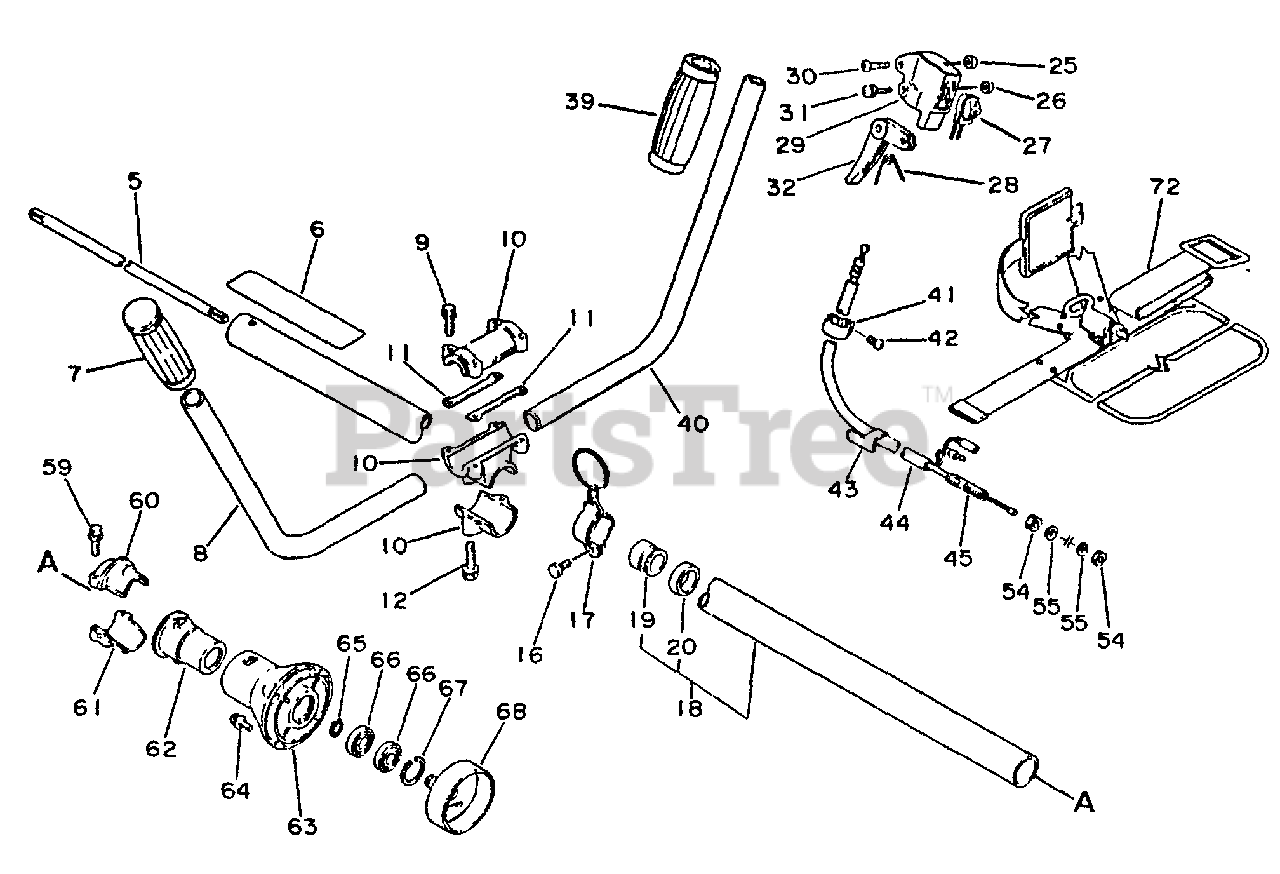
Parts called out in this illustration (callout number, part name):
5	DRIVESHAFT - SOLID
6	LABEL - CAUTION
7	GRIP, HANDLE - LEFT
8	HANDLE, FRONT - LEFT
9	SCREW - 5X25
10	HANDLE BRACKET KIT
12	SCREW - 6X30
16	HANGER KIT
17	BOLT - 5X12
18	MAIN PIPE ASSY
25	LOCKNUT - 5
27	IGNITION SWITCH ASSY
28	SPRING, TRIGGER
29	BRACKET, THROTTLE
30	SCREW - 5X30
31	SCREW - 5X30
32	TRIGGER, THROTTLE
39	GRIP, HANDLE
42	SCREW - 5X10
44	TUBE - VINYL
45	CABLE, THROTTLE
55	WASHER - 6
59	BOLT - 5X25
60	CLAMP, MAIN PIPE
61	CLAMP, MAIN PIPE
63	CASE, CLUTCH
64	BOLT - 5X16
65	RING, RETAINING - 12
66	BEARING, BALL - 6001
67	RING, RETAINING - 28
68	DRUM, CLUTCH
72	SHOULDER STRAP ASSY
